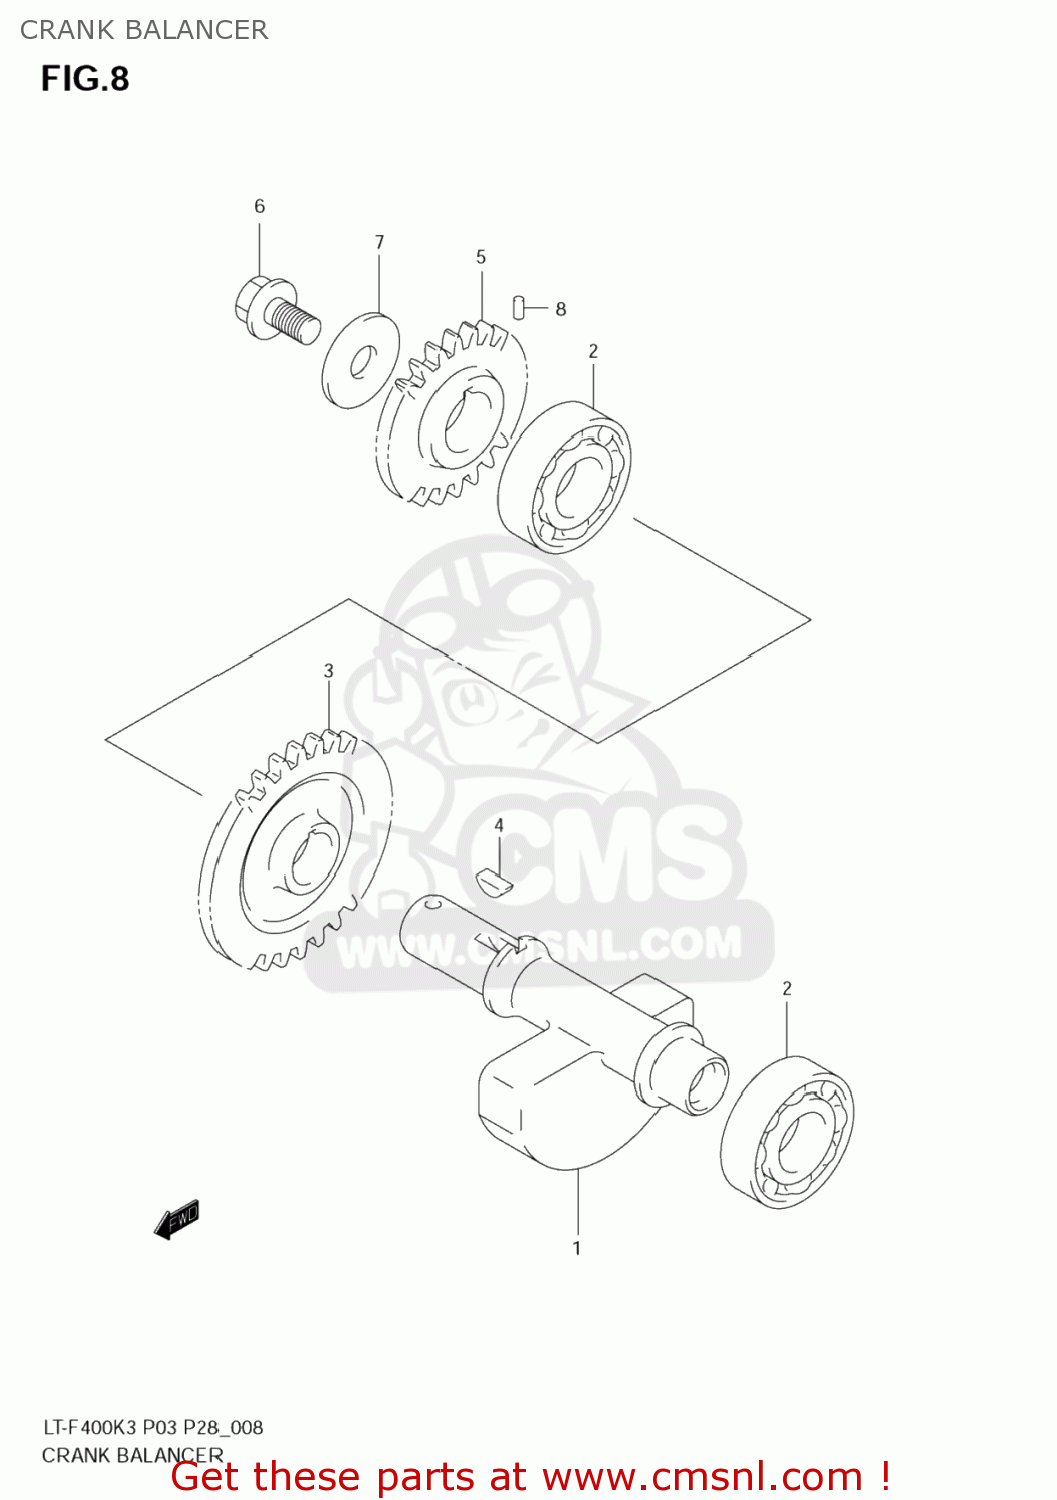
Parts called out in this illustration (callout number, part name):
1	BALANCER,CRANK
2	BEARING(20X47X14)
3	GEAR,CRANK BALANCER DRIVEN
4	KEY
5	GEAR,OIL PUMP DRIVE
6	BOLT(10X20)
7	WASHER
8	PIN
